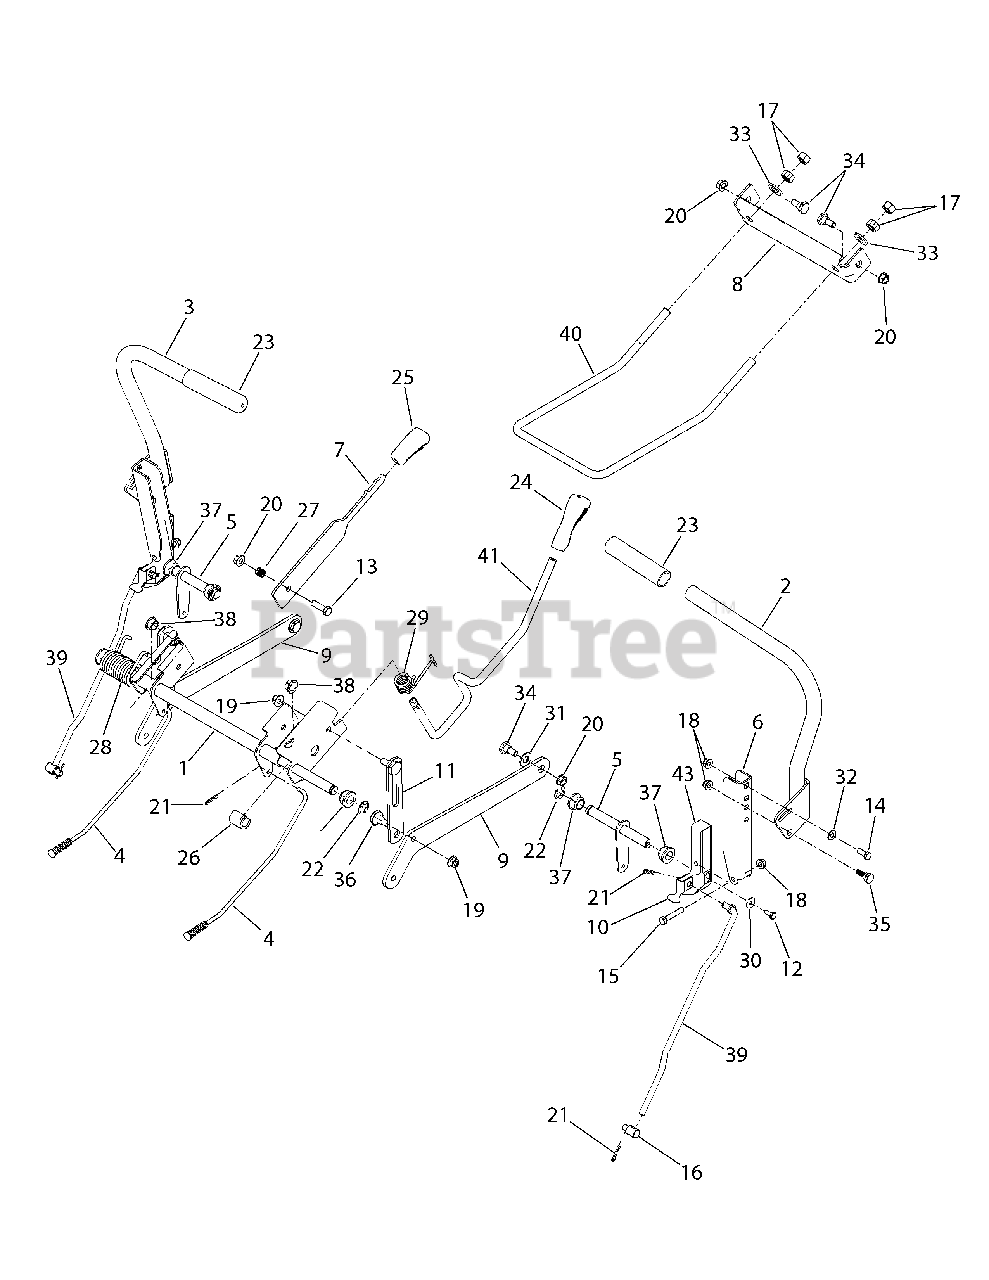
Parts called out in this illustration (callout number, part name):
5	Shaft, Damper Control
6	Bracket, Lapbar Pivot
10	Bracket, Actuator
12	Screw, Hex Cap Lock, 1/4-20 x .625 Gr5
13	Screw, Hex Cap, 3/8-16 x 1.25 Gr5
14	Screw, Hex Cap, 5/16-18 x .75 Gr5
15	Screw, Hex Cap, 5/16-18 x 1.75 Gr5
16	Ferrule, 3/8-24 x .375
17	Nut, Hex, 1/2-13 GR5
18	Nut, U Type Speed, 5/16-18 GrF
19	Nut, Hex Insert Flange Lock, 3/8-18 GrF
20	Nut, Hex Flange Lock, 3/8-16 GrF
21	Pin, Internal Cotter
22	‘E` Ring
23	Grip, Lapbar
24	Grip, Handle
25	Grip, Brake Handle
26	Spacer, .621 ID x 1.0
27	Spring, Compression, .5 x.5
28	Spring, Torsion
29	Spring, Torsion RZT
30	Washer, Bell, .265 .75 x .062
31	Washer, Flat, .51 x 1.00 x .06
32	Washer, Flat, .344 x .6888 x 065
33	Washer, Flat, .531 x 1.062 x .134 HT
34	Screw, Shoulder, .496 x .336:3/8-16
35	Screw, Shoulder, .437 x .268:5/16-18
36	Screw, Shoulder, .5 x .434
37	Bearing, Hex Flange
38	Bearing, Flange, .625 x .938 x .344
39	Rod, Lapbar Control
40	Rod, Deck Front Hanger
41	Rod, Deck Lift Handle
43	Hub, Lap Bar Control
